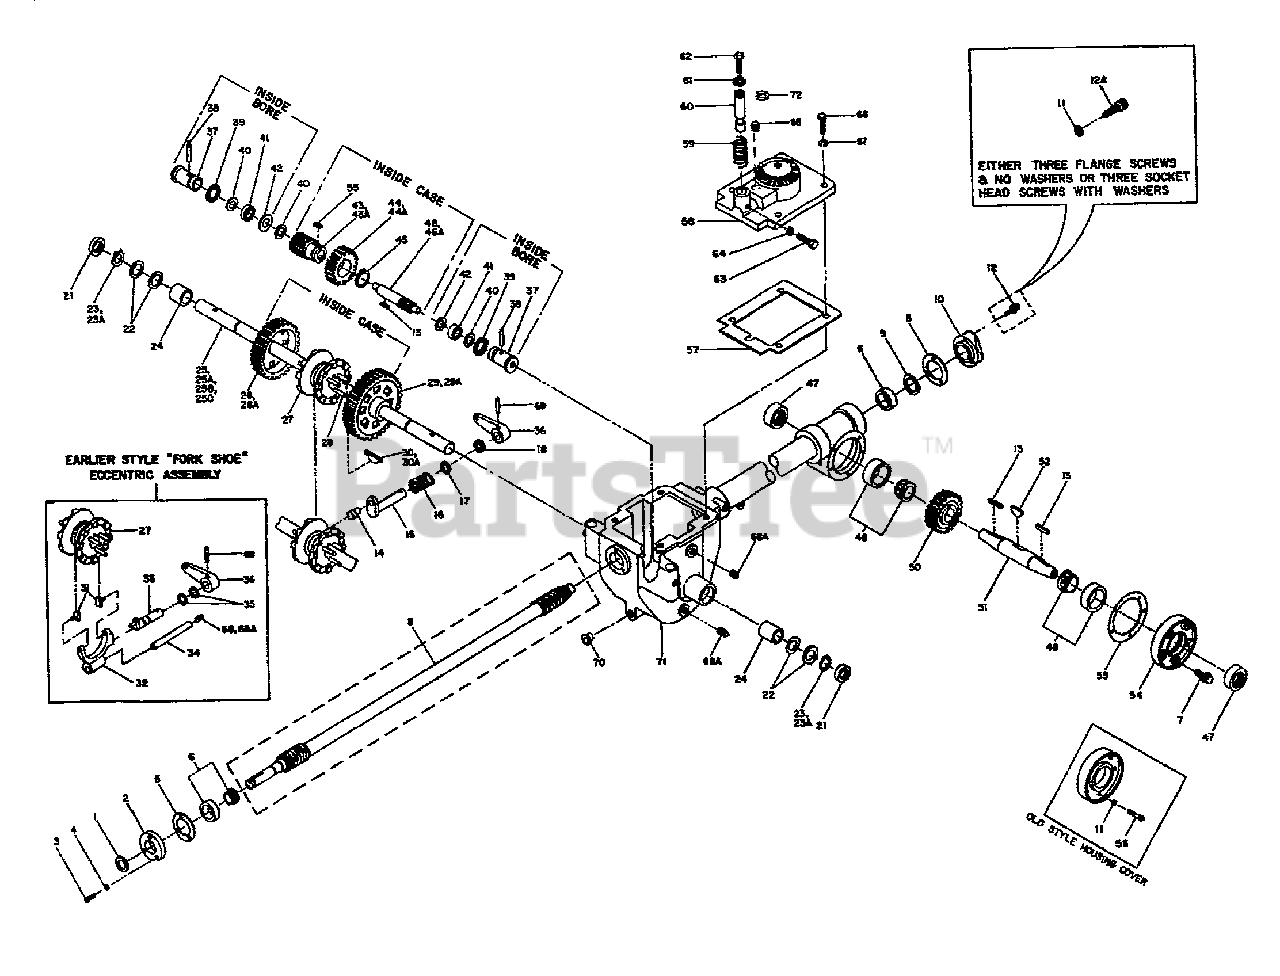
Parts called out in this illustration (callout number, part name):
1	SEAL-PINION SHAFT PT/85030/00
2	COVER-FRONT
3	SCR-HH 1/4-20X.75 G5 ZP
4	WASHER-LK .25 ZP
5	GASKET-BRG COVER
6	KIT-BRG CONE&RACE-DRIVESHAFT
7	SCR-HH 1/4-20X.625
8	KIT-DRIVESHAFT HORSE
9	SHIM-1.75X1.5X.01
9	SHIM-1.75X1.5X.03
9	SHIM-1.75X1.5X.005
10	CAP-REAR #1115
11	WASHER-LK .25 HI-COLLAR
12	SCR-HFLK 1/4-20X.875
12A	SCR-HXSKT 1/4-20X1.0
13	KEY-.188 SQX1.0
14	PIN-.375 X .72
15	SHAFT-ECCENTRIC HORSE TLR
16	SPRING .845 X 1.25
17	WASHER # .875 X .65 X .06
18	SEAL-OIL ECCENTRIC
21	SEAL-OIL WHEELSHAFT
22	SHIM-1.375X1.015X.062
22	SHIM-1.375X1.015X.03
22	SHIM-1.375X1.015X.015
22	SHIM-1.375X1.015X.01
22	SHIM-1.375X1.015X.005
23	RING-HEAVY EXT .906 ID
23A	RING-RETAINING 5100-100
24	BUSHING-1.25X1.005X1.5
25	KIT-WHEELSHAFT
25A	KIT-WHEELSHAFT
25B	KIT-WHEELSHAFT
25C	KIT-WHEELSHAFT
26	GEAR-SPUR 46 TEETH MACH
26A	GEAR-SPUR-50 TEETH-MACH
27	CLUTCH-MACH
29	GEAR-SPUR 56 TEETH MACH
29A	GEAR-SPUR 60 TEETH-MACH
30	KEY-HI PRO .25X1.812
30A	KEY-HI PRO .25X1.062
31	PIN-.375 X .72
32	CLUTCH FORK
33	SHAFT-ECC WITH O RING
34	PIN-.5X4.0 FORK #
35	RING-O .625 X .438
36	LEVER-ECC. #1029
37	PLUG-PINION BRG W/RING
38	PIN-SPIROL .25 X 2.0
39	RING-O 1 ID
40	SHIM-1.234X1.015X.033
40	SHIM-1.234X1.015X.062
40	SHIM-1.234X1.015X.01
41	BRG-BALL (7 BALLS)
42	WASHER-# 1X.484X.06
43	GEAR-SPUR 20 TEETH MACH
43A	GEAR-SPLINE-16 TEETH-MACH
44	GEAR-WORM 36 TEETH MACH
44A	GEAR-WORM-30 TEETH-MACH
45	RING-RETAINING 5100-150
46	GEAR-SPLINE 10 TEETH MACH
46A	GEAR-SPLINE 6 TEETH MACHINE
47	SEAL-OIL TILLERSHAFT
48	TAPERED, BEARING & CUP
50	WORM GEAR
51	SHAFT-TILLER W/KEY
52	KEY-WOODRUFF .25X1.12
53	GASKET-TILLER COVER
54	COVER-W/SCRS(TLR) (9780)
57	GASKET-TRANS COVER
58	ASSM-COVER W/BOLT-HORSE
59	SPRING .78 X 2.125
60	ASSM-NEUTRAL PLUNGER
62	BOLT-HH 3/8-16X1.5 FTH ZP
63	SCR-HH 5/16-18X1.0 G5 ZP
64	NUT-HEX 5/16-18 ZP
65	PLUG-PIPE 3/8 NPT
66	BOLT-HH 3/8-16X1.5 FTH ZP
67	WASHER-LK .375 @ DEPL
68	PLUG-PIPE 3/8 NPT
68A	PLUG-PIPE 1/4 NPT
70	PLUG-CAP (RED)
71	TRANSMISSION CASE, HOUSING & TUBE ASSEMBLY
72	RING-KLIP EXT .594 ID ZP
